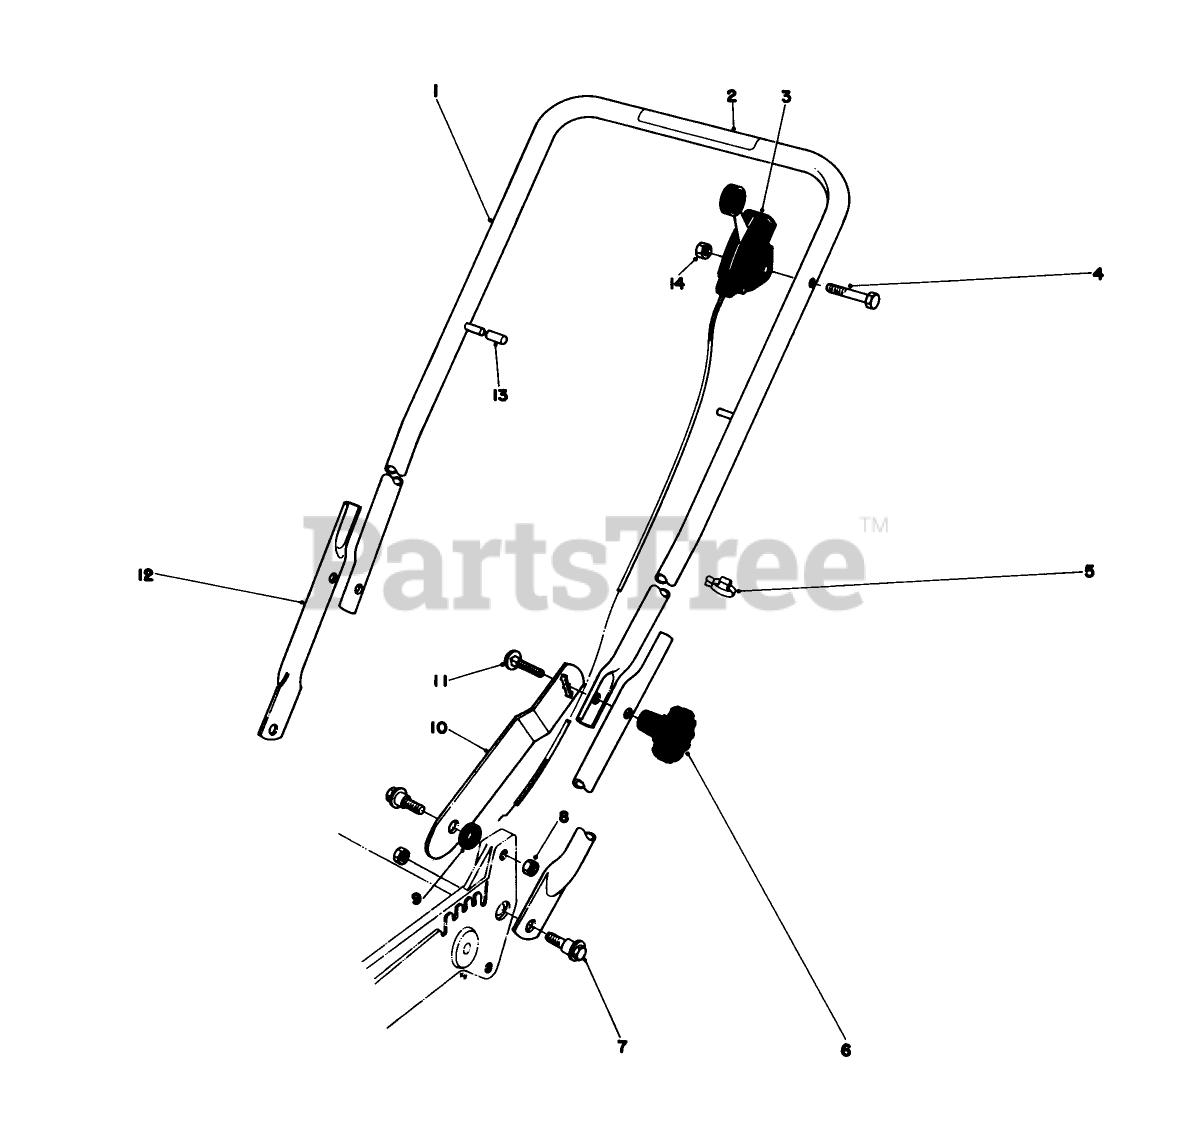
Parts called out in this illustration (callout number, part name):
4	SCREW-HH
5	BOWDEN CLIP
9	SPACER
11	BOLT-CAR
